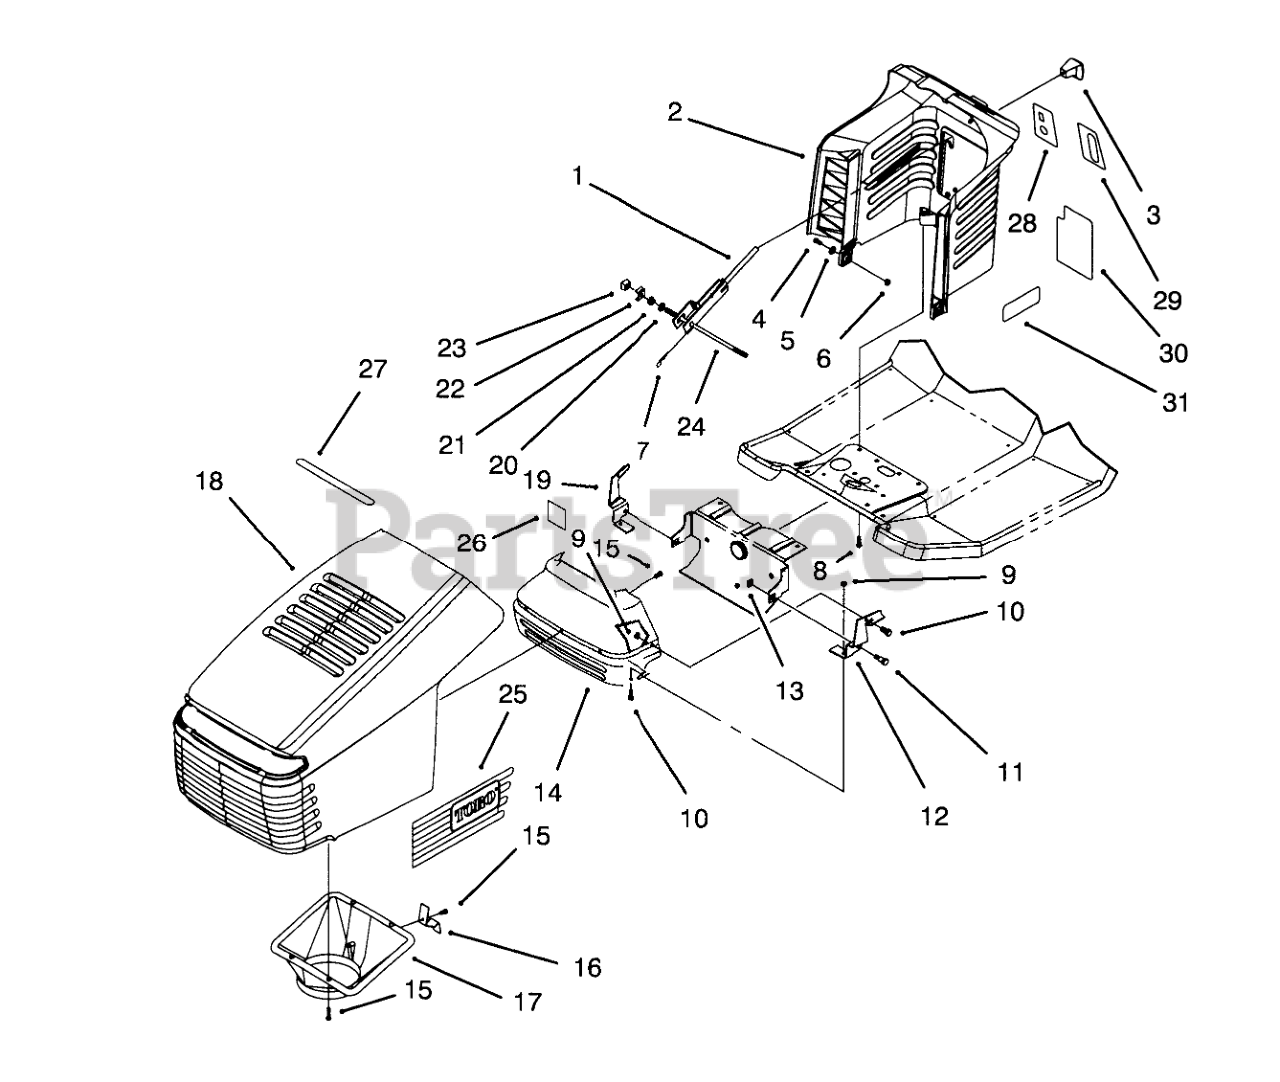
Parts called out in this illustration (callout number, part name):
1	Lever-Deck Engage
2	Tower-Steering
3	SHIFT KNOB
4	SCREW-HH
5	WASHER-PLAIN
6	NUT-LOCK, NI
7	PIN-COTTER
8	SCREW-HWH
9	NUT-LOCK, NI
10	SCREW-HH
11	BOLT-SHOULDER
12	Bracket-Hinge L.H.
13	NUT-RETAINER
14	Shield-Heat
15	SCREW-PLASTITE
16	HOOD LATCH
17	DUCT-AIR
18	HOOD ASM
19	Bracket-Hinge R.H.
20	WASHER-FLAT
21	NUT-FLANGE
22	ROD-CLAMP PIVOT
23	NUT-WEDGE
24	ROD-TOWER PIVOT
25	DECAL - HOOD RIGHT
26	TAPE-FOIL
27	DECAL-AIR DUCT
28	DECAL-IGNITION/LIGHTS
29	DECAL
30	DECAL-DECK, ENGAGE
31	DECAL - TOWER
